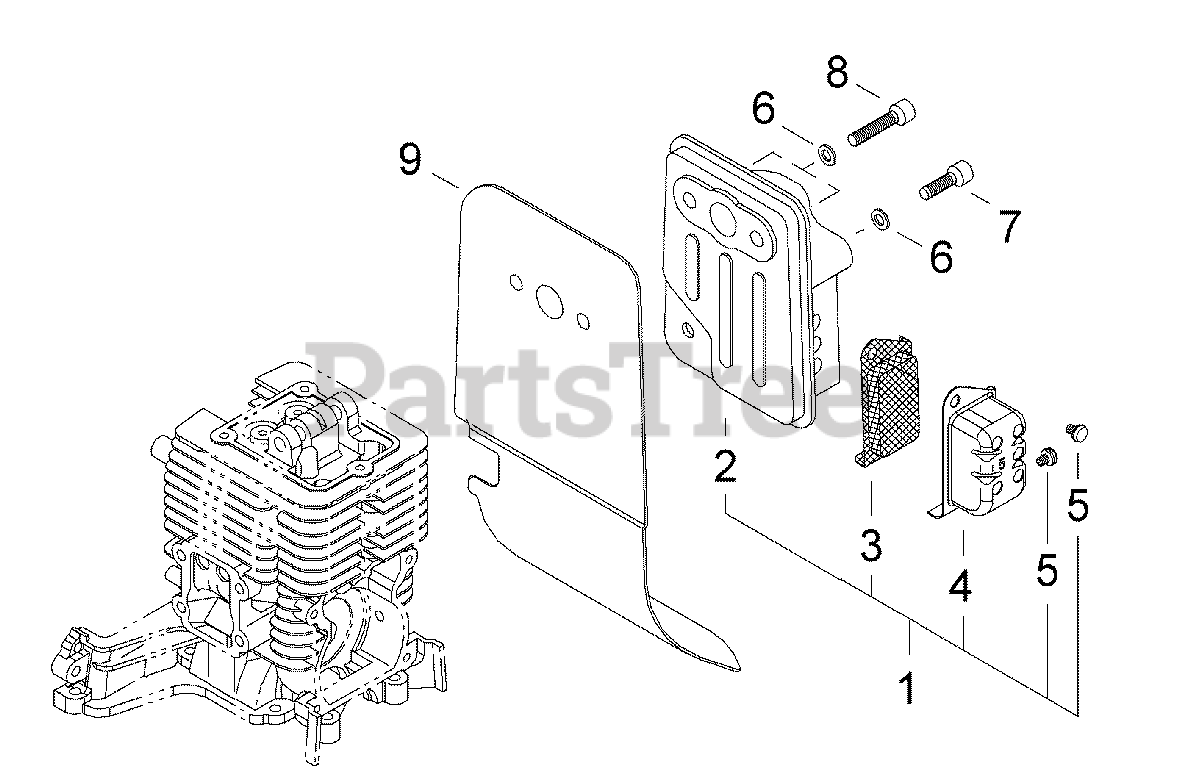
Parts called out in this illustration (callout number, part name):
1	MUFFLER ASSY
2	MUFFLER
3	SCREEN, SPARK ARRESTER
4	GUIDE, EXHAUST
5	SCREW M4×6
6	WASHER, FLAT 5.5×10×0.8
7	BOLT 5×16
8	BOLT M5×25
9	HEAT SHIELD, EXHAUST
